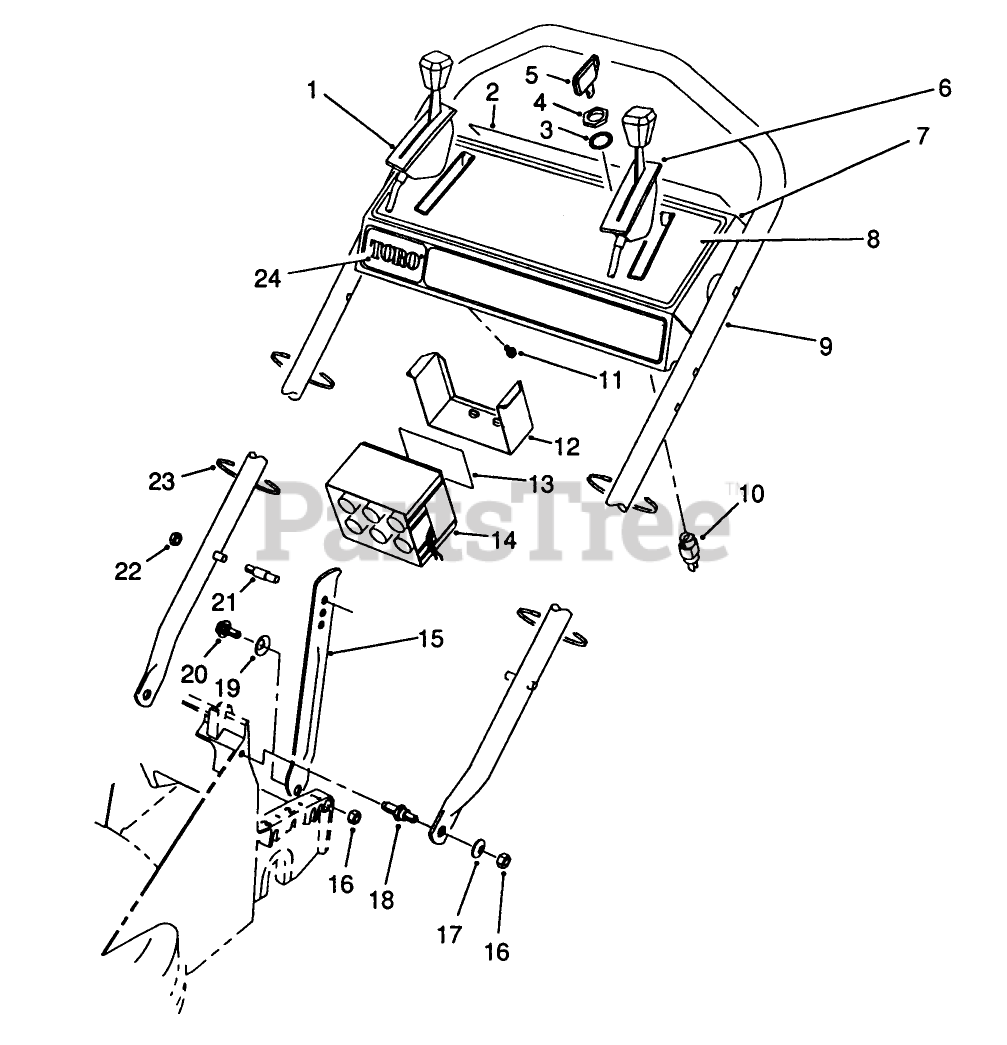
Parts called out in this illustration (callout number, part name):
3	KEY-IGNITION
4	NUT-HH
5	WASHER-LOCK
10	STARTER SWITCH ASM
11	SCREW-HWHTF
14	BATTERY ASSEMBLY,WET
16	NUT-LOCK, NI
17	WASHER-PLAIN
19	WASHER-BELLEVILLE
21	HANDLE PIN
22	NUT-LOCK, NI
23	TIE-CABLE
